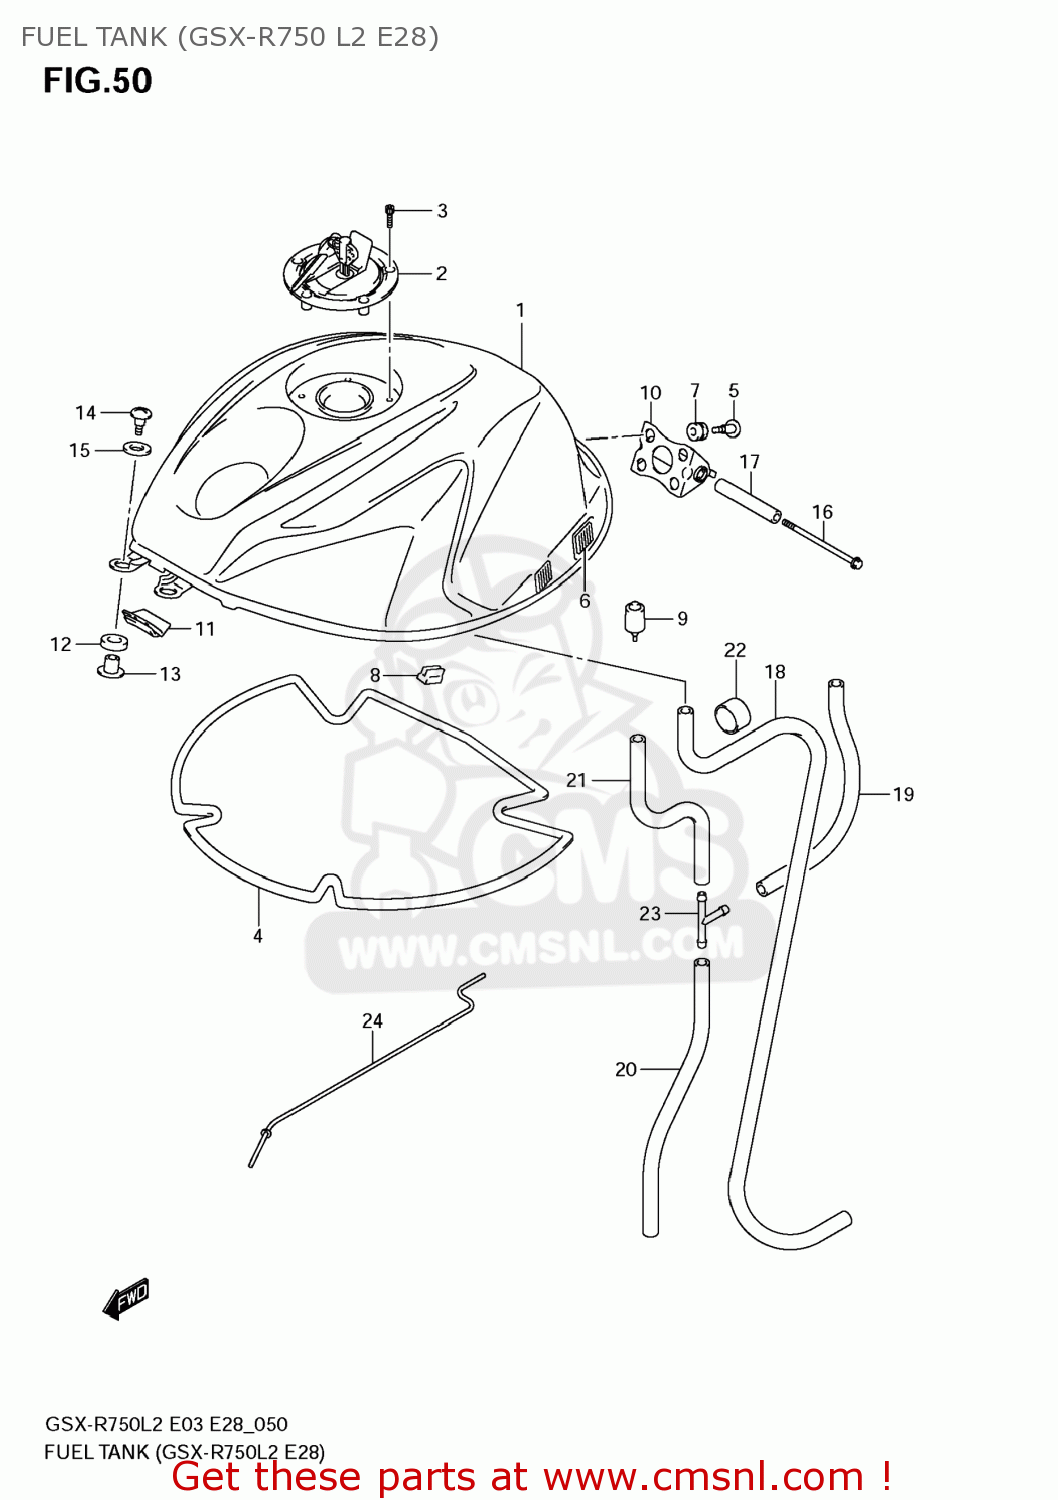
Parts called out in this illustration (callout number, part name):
1	TANK ASSY FUEL
2	CAP SET,FUEL TANK
3	BOLT(5X20)
4	SHIELD,FUEL TANK HEAT
5	SCREW,FUEL TANK RR BRACKET
6	FASTENER
7	CUSHION
8	CUSHION,FUEL TANK COVER
9	CUSHION,FUEL TANK RR
10	BRACKET,FUEL TANK NO.1
11	RUBBER,FUEL TANK FR
12	CUSHION,FUEL TANK FR
13	SPACER,FUEL TANK FR
14	SCREW(6X25)
15	WASHER(6.5X22X1.6)
16	BOLT(6X110)
17	SPACER,FUEL TANK RR
18	HOSE,FUEL TANK WATER DRAIN
19	HOSE,FUEL TANK BREATHER NO.1
20	HOSE,FUEL TANK BREATHER NO.2
21	HOSE,VACUUM
22	HOSE(12X16X600)
23	3 WAY
24	STAY,FUEL TANK
